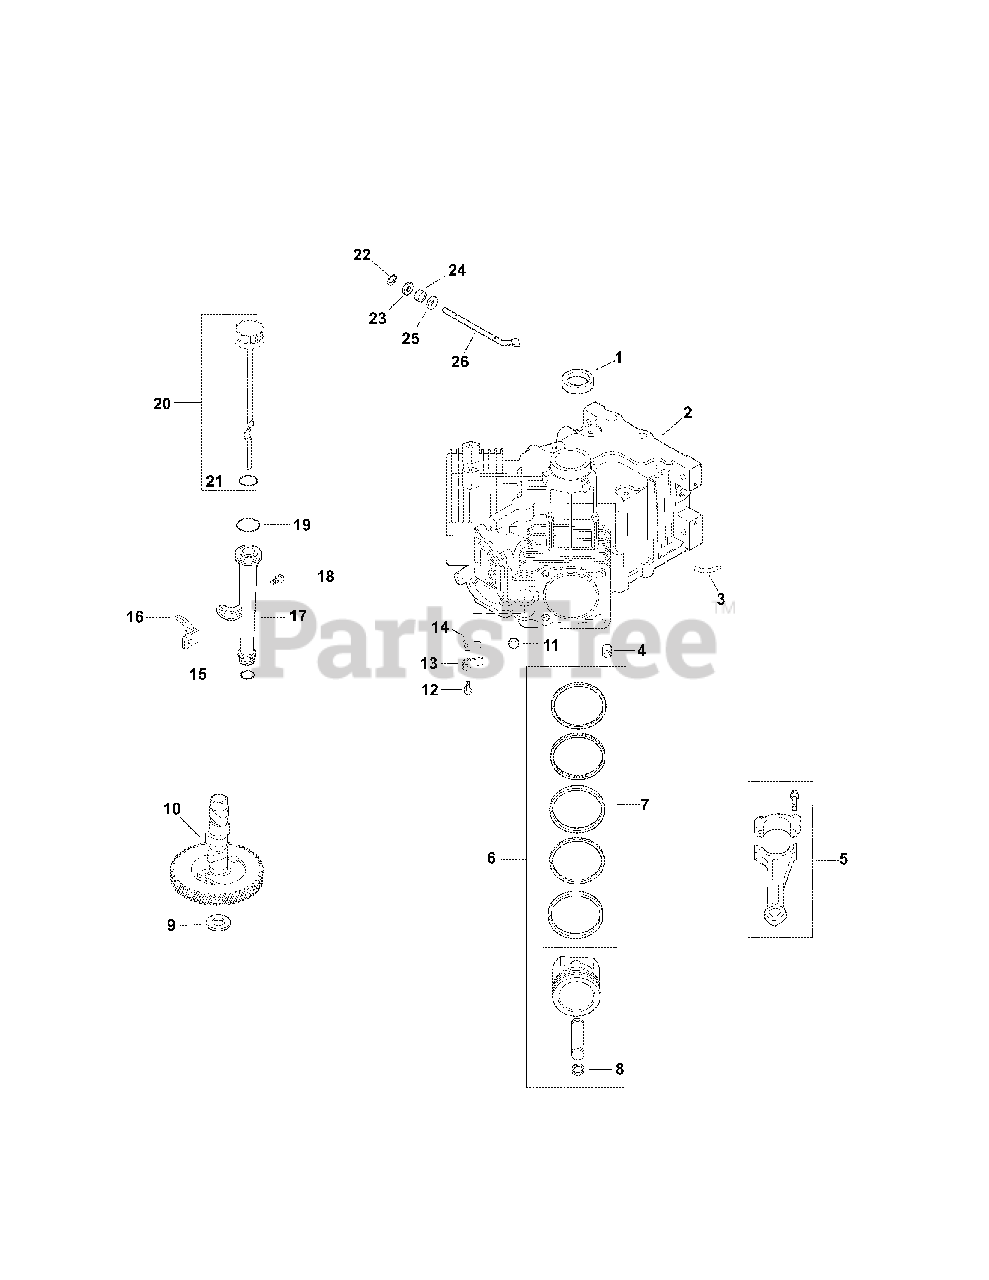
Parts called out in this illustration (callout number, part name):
1	Seal, front oil
4	Pin, locating
5	ConnectIng Rod (Std.)
5	Connecting Rod (.25)
6	Piston w/Ring Set (Std.) (Includes 7,8)
6	Piston w/Ring Set (.08)
6	Piston w/Ring Set (.25)
6	Piston w/Ring Set (.50)
7	Ring set (Std. & .08)
7	Ring set (.25)
7	Ring set (.50)
8	Retainer, piston pin
9	Shim, camshaft (red .032")
9	Shim, camshaft (black .04")
9	Shim, camshaft (white .02 8")
9	Shim, camshaft (blue .03")
9	Shim, camshaft (yellow .034")
9	Shim, camshaft (green .036")
9	Shim, camshaft (gray .038")
10	Camshaft
12	Screw, flg thd frm M5x0.8x10
13	Retainer, reed
14	Reed, breather
15	O-Ring, lower oil fill tube
16	Bracket, oil fill tube
17	Tube, oil fill
18	Screw, flg thd frm M5x0.8x16
19	O-Ring, upper oil fill tube
20	Dipstick assembly (Includes 21)
21	O-Ring, dipstick
22	Ring, retainer
23	Washer, flat 9 mm
24	Seal, governor cross shaft
25	Washer, flat 11/32"
26	Shaft, governor cross
